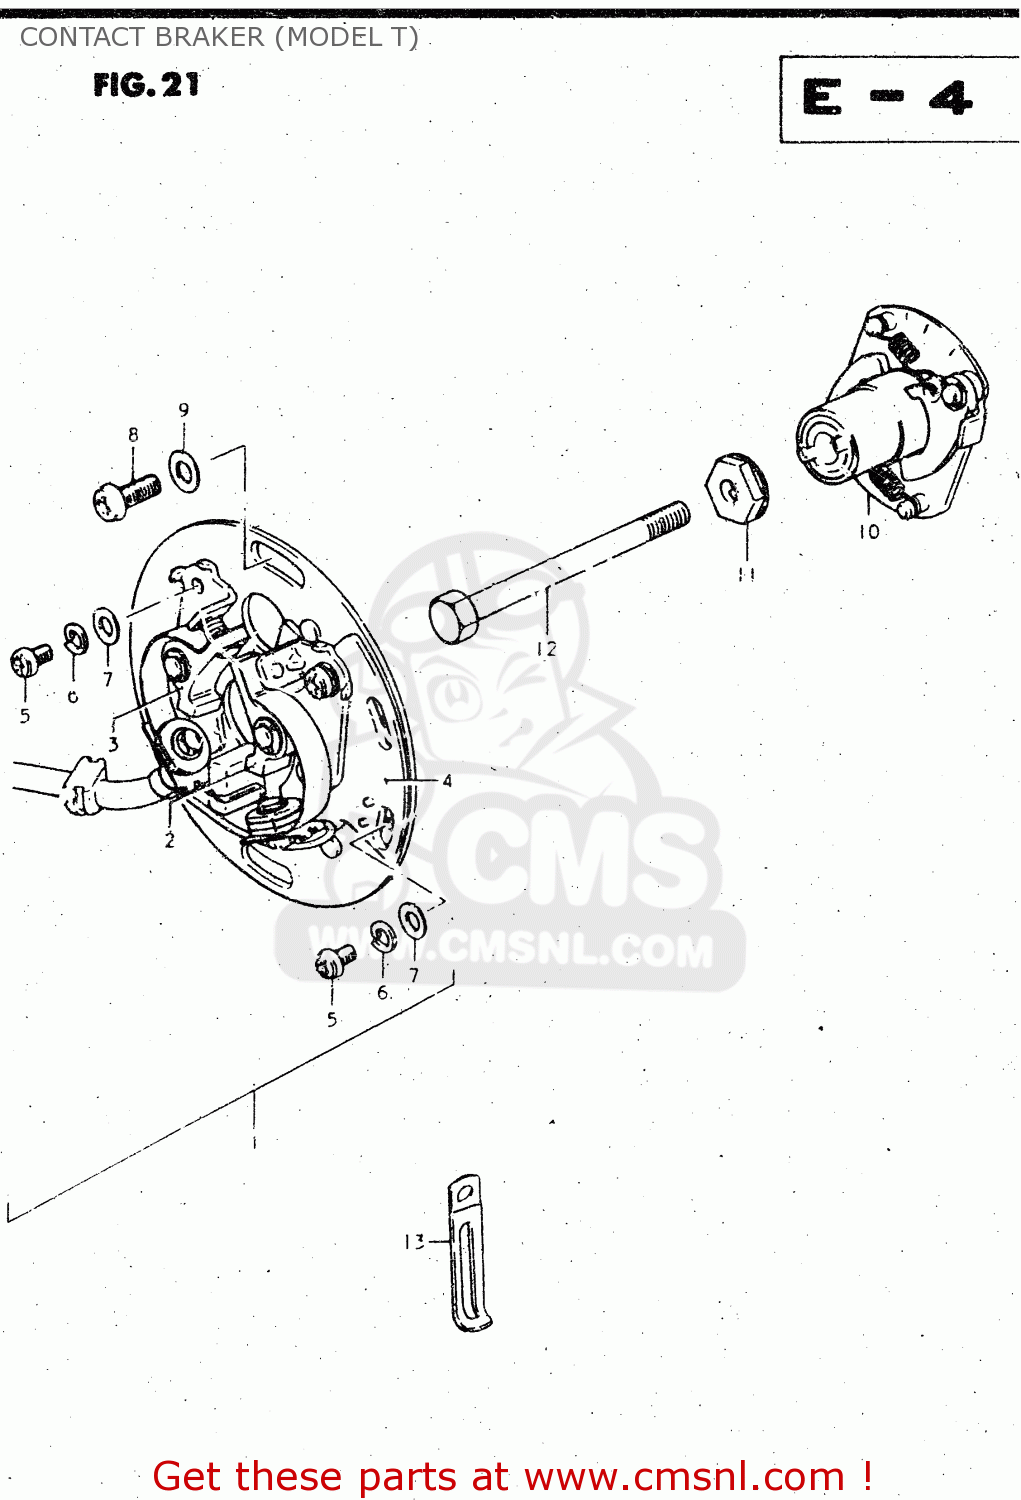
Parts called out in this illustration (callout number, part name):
1	BREAKER ASSY, CONTACT
2	POINT ASSY,CONTACT,R
3	POINT ASSY,CONTACT,L
4	PLATE,CONTACT POINT
5	SCREW 4X6
6	LOCK WASHER
7	WASHER
8	SCREW(5X12)
9	WASHER
10	GOVERNOR ASSY, ADVANCE
11	WASHER,CONTACT BREAKER
12	BOLT 6X60
13	CLAMP L:35
